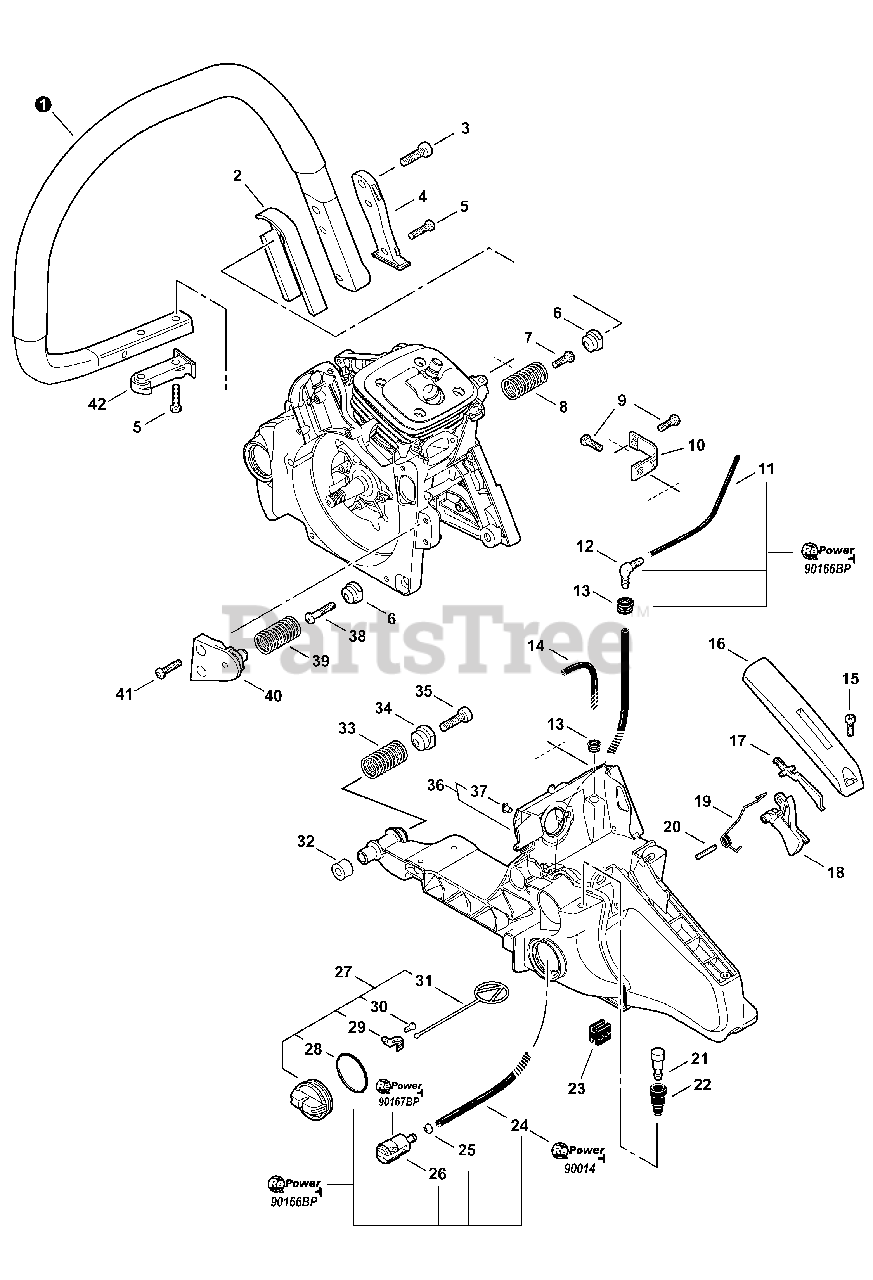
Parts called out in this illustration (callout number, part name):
1	HANDLE, FRONT
2	HOLDER, SPRING
3	BOLT, TORX 6×20
4	MOUNT, HANDLE
5	BOLT, TORX 5×20
6	HOLDER, SPRING Ø14.4
7	BOLT, TORX 5×16
8	SPRING, COMPRESSION Ø17×38.4×2.6
9	BOLT, TORX 5×16
10	STRAP, SAFETY
11	PIPE, FUEL 3×6×135
12	CONNECTOR, PIPE
13	GROMMET
14	PIPE, IMPULSE 3×6(8)×160
15	BOLT, TORX 4×12
16	COVER, HANDLE
17	LEVER, THROTTLE LOCKOUT
18	TRIGGER, THROTTLE
19	SPRING, TORSION
20	PIN, SPRING 4×25 SUS
21	VENT ASSY
22	GROMMET, VENT
23	GROMMET, LEAD
24	PIPE, FUEL 3×5×120 BLACK
25	CLIP Ø6
26	FILTER, FUEL
27	CAP ASSY, FUEL
28	O-RING 29
29	RETAINER, CONNECTOR
30	SCREW, TAPPING 3×8
31	CONNECTOR, CAP L= 60 MM
32	CUSHION 10
33	SPRING, COMPRESSION Ø20×40×3.3
34	HOLDER, SPRING Ø17
35	BOLT, TORX 6×20
36	HANDLE, REAR
38	BOLT, TORX 5×25
39	SPRING, COMPRESSION Ø17×36.7×2.6
40	HOLDER, SPRING
41	BOLT, TORX 5×20
42	MOUNT, HANDLE
